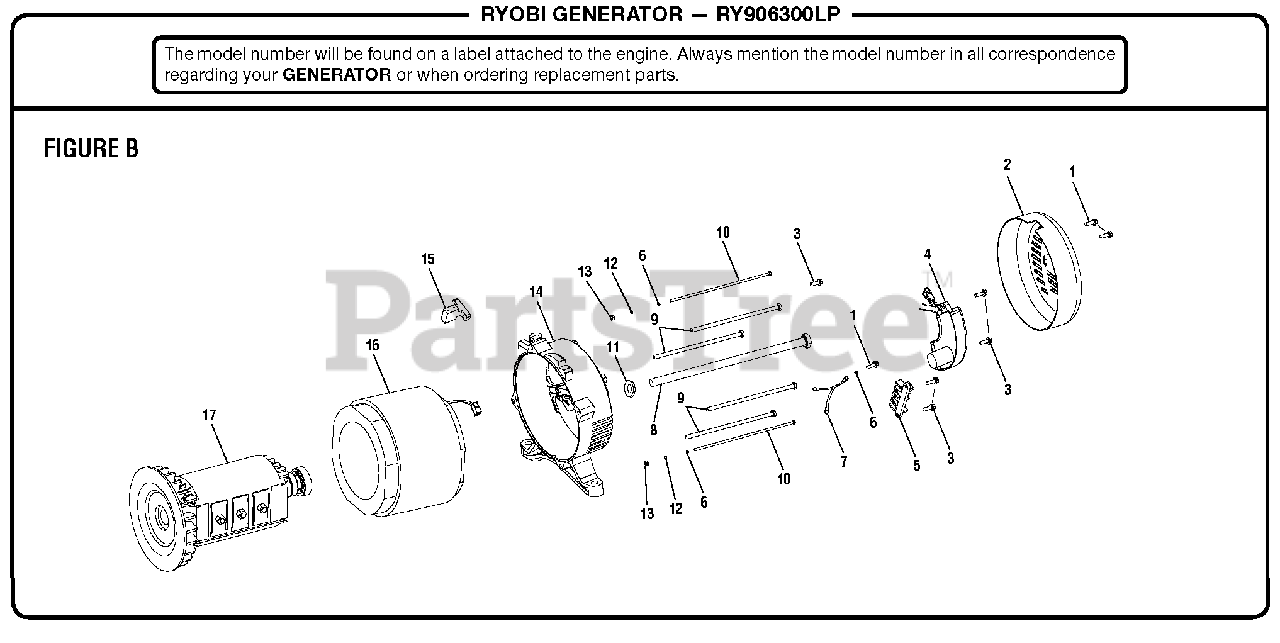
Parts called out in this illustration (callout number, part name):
1	Bolt (M5 x 12 mm, Hex Flange Hd.)
2	Brush Cover
3	Bolt (M5 x 16 mm, Hex Flange Hd.)
4	Automatic Voltage Regulator
5	Brush Assembly
6	Lock Washer (M5)
7	Grounding Wire
8	Rotor Bolt
9	Bearing Carrier Bolt
10	Stator Bolt
11	Rotor Bolt Washer
12	Washer (M5)
13	Hex Nut (M5)
14	Bearing Housing
15	Grounding Post Assembly
16	Stator Assembly
17	Rotor Assembly
